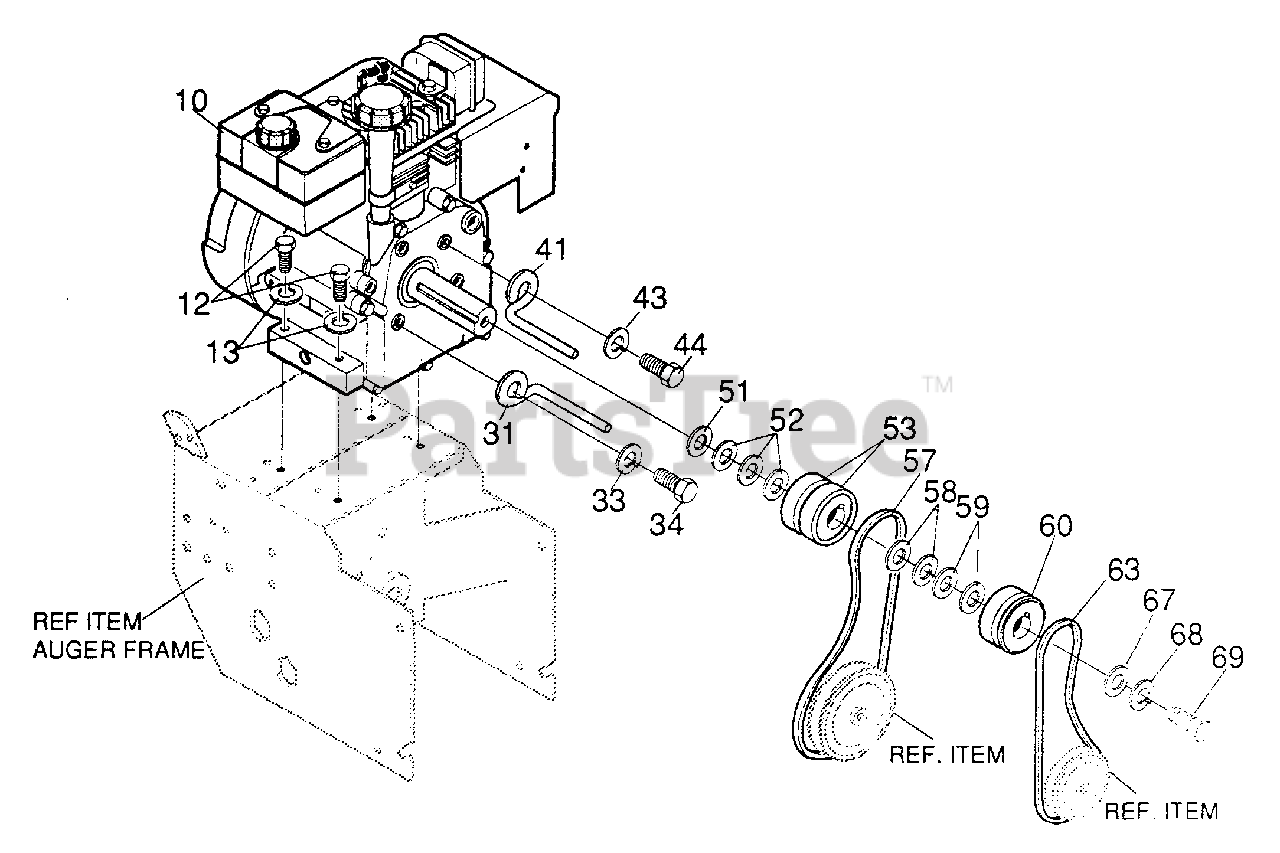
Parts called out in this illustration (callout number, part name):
10	ENGINE, 5 HP
12	SCREW, 5/16-180.25
13	WASHER, HVSPTLK .328 x .60 x .09
31	GUIDE, ROD BELT, RH
33	WASHER, HVSPTLK .328 x .60 x .09
34	SCREW, 5/16-24 x .625 HHC
41	GUIDE, ROD BELT RH
43	WASHER, HVSPTLK .328 x .60 x .09
44	SCREW, 5/16-24 x .625 HHC
51	WASHER, CRANKSHAFT
52	FLATWASHER, .752 x .91 x .02
53	PULLEY, HALF V31- 2.00 x .752 ID
54	WASHER, FLAT .752 x .91 x .02
57	BELT, V 3L 33.13 LONG
58	FLATWASHER, .7650 .12 x .06
59	FLATWASHER, .752 x .91 x .02
60	PULLEY, ENGINE V41
63	BELT, V 4L AUG DRIVE 30.7
67	FLATWASHER
68	WASHER, REGSPTLK.393 x .68 x .10
69	SCREW, 3/8-240.00 NYL
